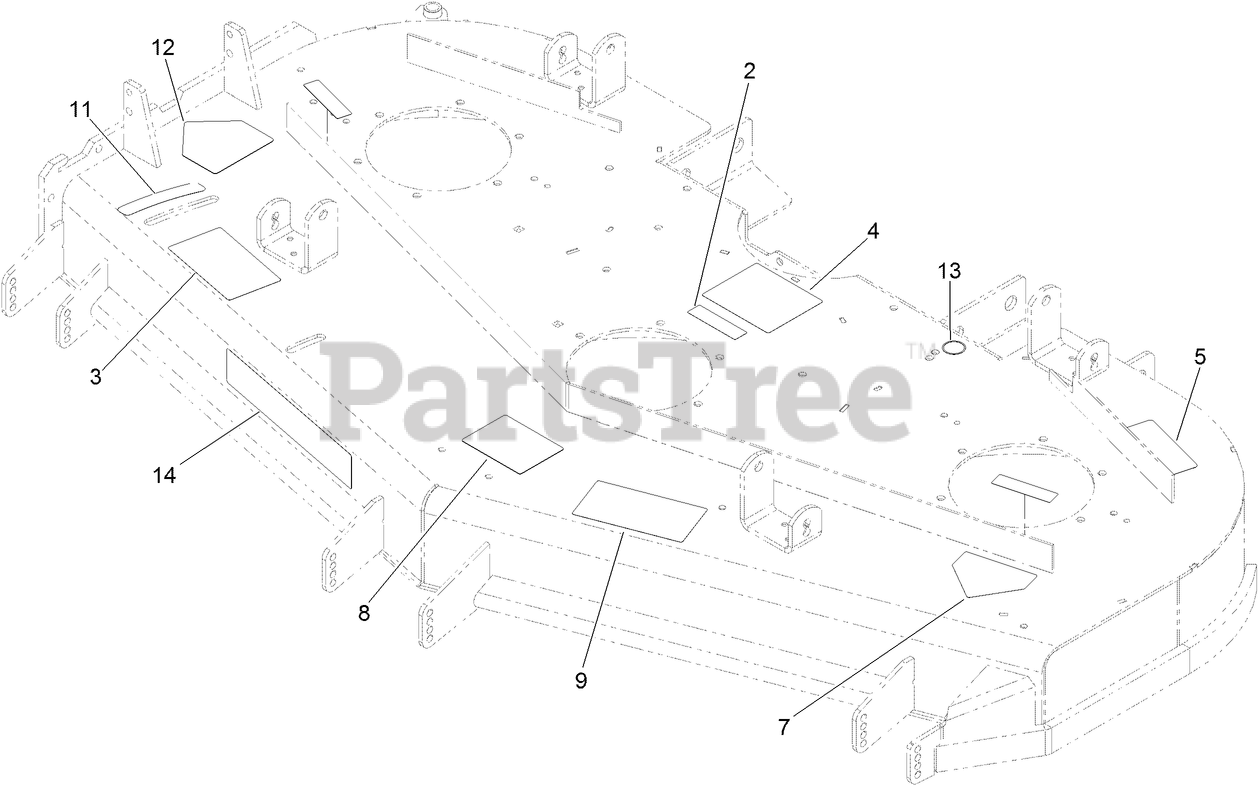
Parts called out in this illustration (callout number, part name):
2	DECAL-COVER, MISSING
3	DECAL-ADJUSTMENT, BAFFLE
4	DECAL-ROUTING, BELT
5	DECAL-TORQUE
7	DECAL-DANGER
8	DECAL-SCALP, ANTI
9	DECAL-DANGER, THROWN OBJECT
11	DECAL-SETTING, BAFFLE
12	DECAL-DANGER
13	DECAL-GREASE
